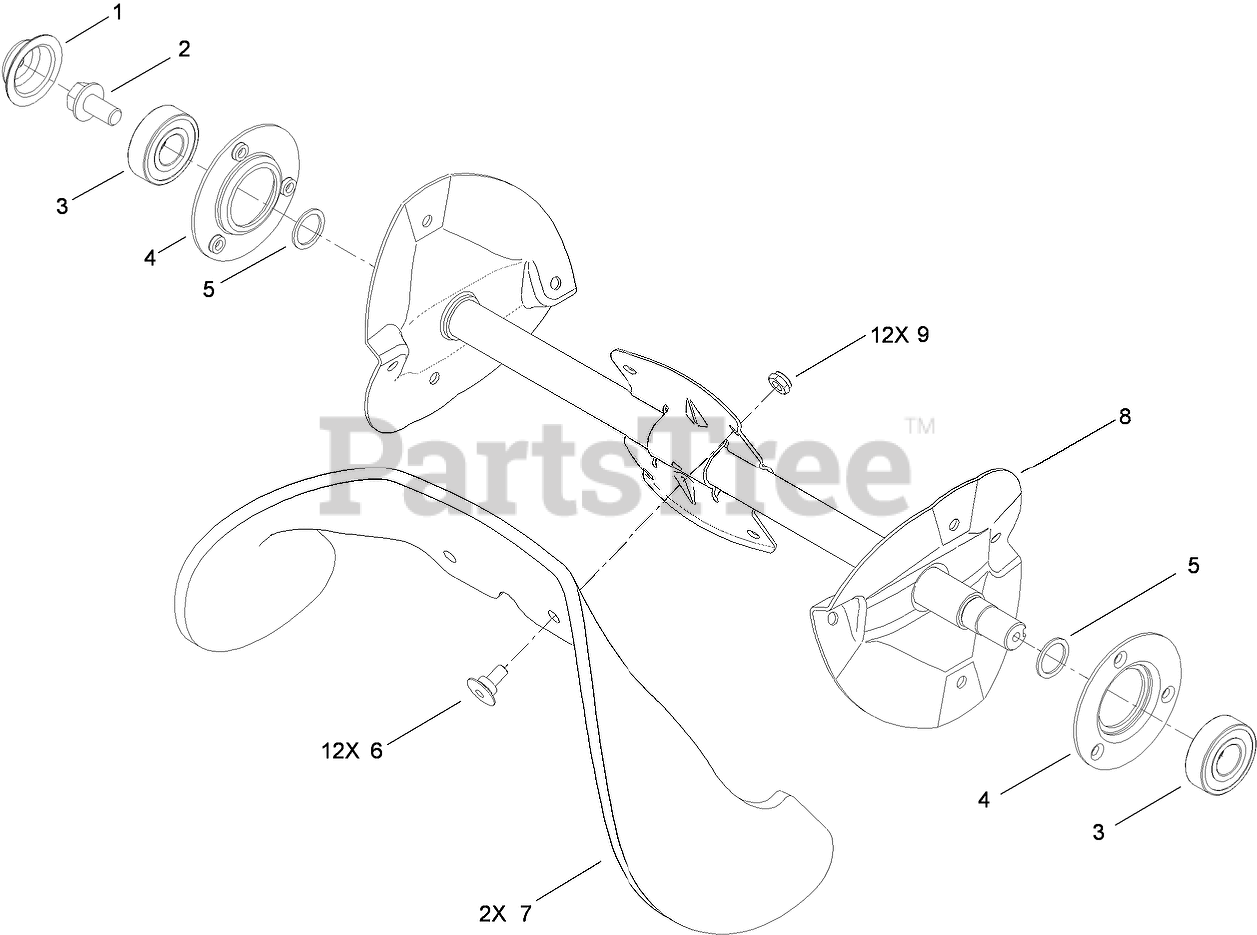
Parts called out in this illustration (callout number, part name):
1	CAP-SIDEPLATE, RH
2	SCREW-HWH
3	BEARING-BALL
4	FLANGE-BEARING
5	WASHER-THRUST
6	SCREW
7	BLADE-ROTOR
8	ROTOR ASM
9	NUT-LOCK, NI
